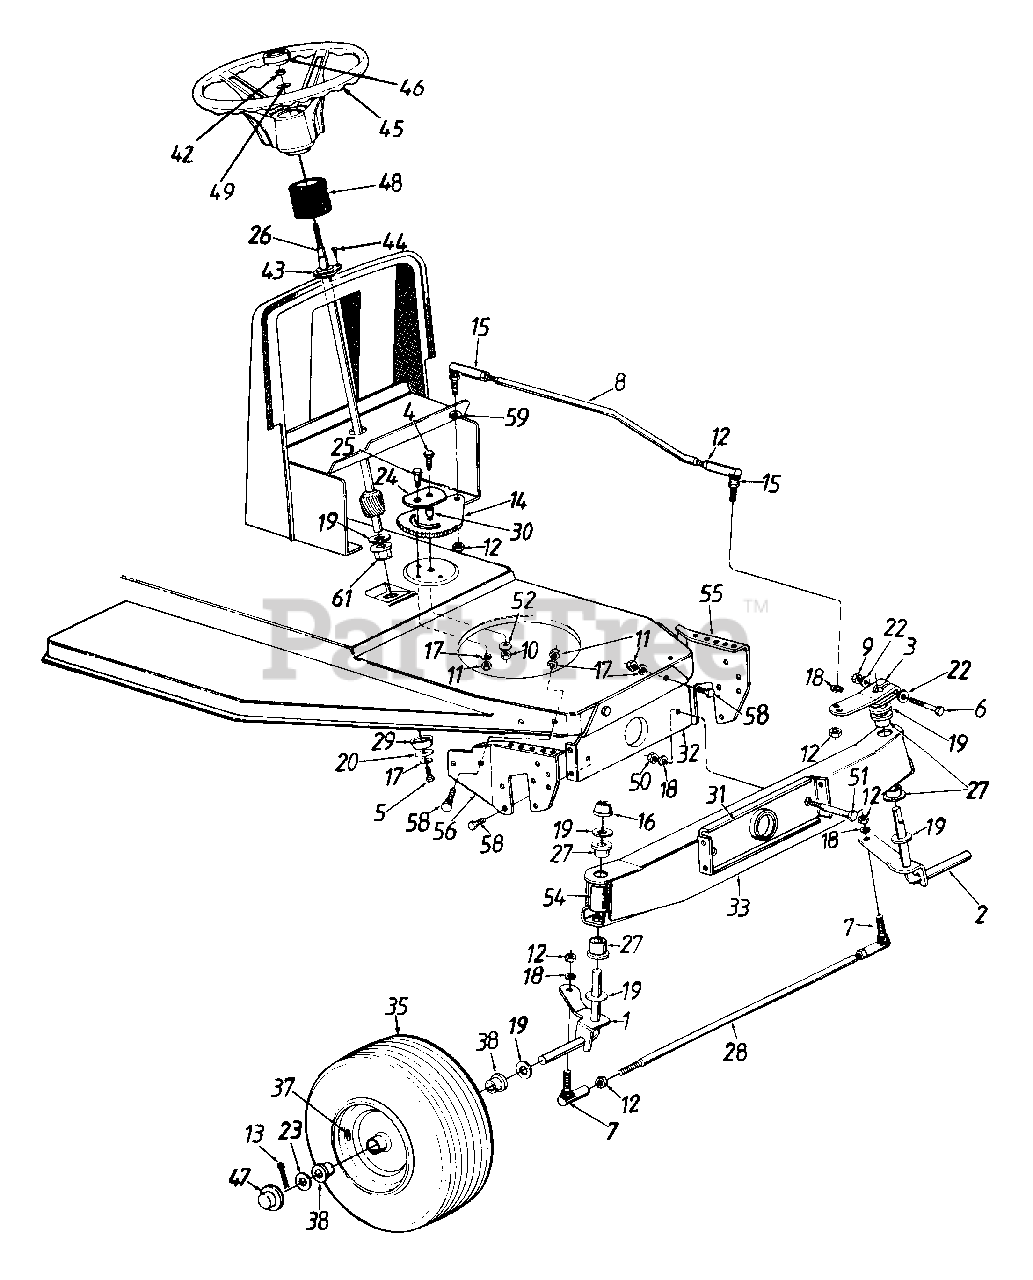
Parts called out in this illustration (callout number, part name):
1	Front Axle Ass'y.- R.H.
2	Front Axle Ass'y.- L.H.
3	Steering Arm
4	Hex Bolt 3/8-24 x 1" Lg.
5	Hex Bolt 5/16-18 x .62" (Spec)
6	Hex Bolt 5/16-24 x 2" Lg.
7	Ball Joint 3/8-24 Thd.
8	Steering Drag Link
9	Hex L-Nut 5/16-24 Thd.
10	Hex Nut 3/8-24 Thd.
11	Hex Nut 5/16-18 Thd.
12	Hex Jam Nut, 3/8-24 Thd.
13	Cotter Pin 1/8 Dia.
14	Steering Gear Segment
15	Drag Link Ball Joint 3/8-24 Thd.
16	Push Cap
17	L-Wash. 5/16" I.D.
18	L-Wash. 3/8" I.D.
19	Fl-Wash..64" I.D. x 1.24"
20	Fl-Wash..340" I.D. x 1.125"
22	Spr. Wash..32" I.D. x .62"
23	Fl-Wash ..635" I.D. x 1.585"
24	Retainer Plate
25	Shld. Bolt .437" Dia. x .350"
26	Steering Shaft
27	Hex Flange Brg..632" I.D.
28	Tie Rod
29	Spacer .985" I.D.
30	Spacer .380" I.D.
33	Pivot Bar Ass'y.
38	Bearing
38	Grease Fitting
42	Hex L-Nut 5/16-24 Thd.
43	Steering Column Brg.
44	Cr-Sunk Scr. #10 x 5/8" Lg.
45	Steering Wheel
46	Steering Wheel Cap
47	Hub Cap
48	Bellow Steering Column
49	Bell-Wash..345" I.D. x .88"
50	Hex Nut 3/8-16 Thd.
51	Shld. Bolt 1/2" Dia. x 2.04"
52	Bell-Wash..39" x 1.38" O.D.
54	Plastic Tube
55	Pivot Bar Side Plate - L.H.
56	Pivot Bar Side Plate - R.H.
58	Hex Wash. Tap Scr. 5/16-18 x .62" Lg.
59	L-Wash. 3/8" I.D. (H.D.)
61	Hex Flange Brg..634" Dia.
